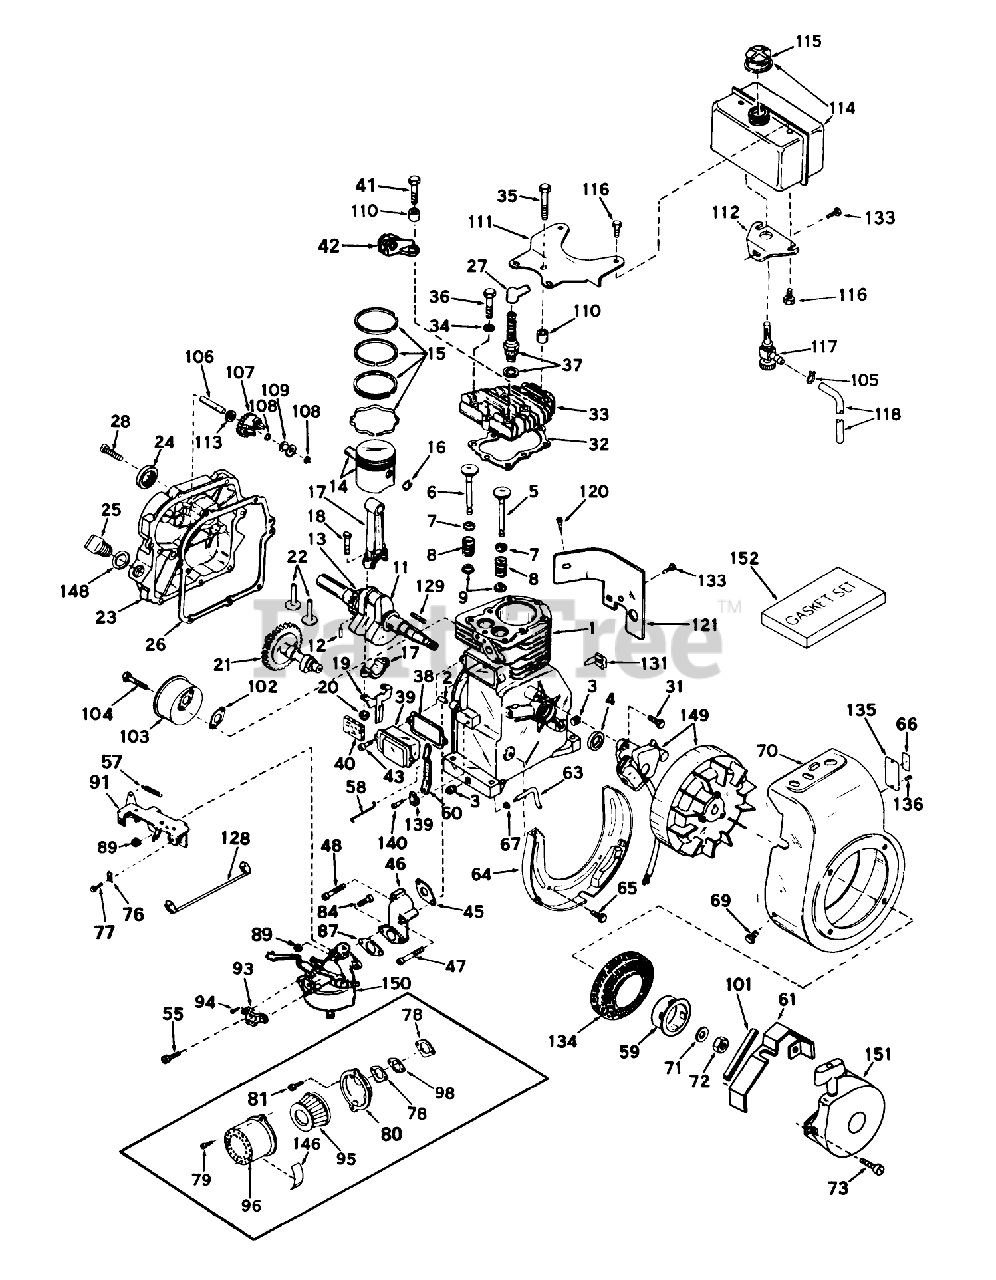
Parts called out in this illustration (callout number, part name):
1	Cylinder Assy. (Incl. Nos. 2,3 4)
2	Pin-Dowel
3	Plug-Drain, Oil (SQH 1/4-18)
4	OIL SEAL
5	Valve, Intake (Incl. Ref. #38, 39 40) (Std.)
5	Valve, Exhaust (1/32" Oversize) (Incl. Nos. 8, 9 10)
6	Valve, Exhaust (Standard) (Incl. Nos. 8, 9 10)
6	Valve, Exhaust (1/32" Oversize) (Incl. Nos. 8, 9 10)
7	Cap-Upper Valve Spring
8	Spring-Valve
9	Cap-Valve, Spring
11	Crankshaft Assy. (Incl.Nos. 12 13)
12	Pin, Groove
13	Gear, Crankshaft
14	Piston Pin Assembly (Incl. 2 of No. 16) (Std.)
14	Piston Pin Assembly (Incl. 2 of No. 16) (.010 Oversize)
14	Piston Pin Assembly (Incl. 2 of No. 16) (.020 Oversize)
15	Piston Ring Set Std.
15	Piston Ring Set .010 O.S.
15	Piston Ring Set .020 O.S.
16	Ring-Retaining, Piston Pin
17	Rod Assy., Connecting (Incl. Ref. #17)
18	Bolt, Connecting
19	53020/22 GIL.HYDRO
20	LOCKNUT
21	Camshaft (Compression Release
22	Lifter-Valve
23	Cover, Cylinder (Incl. Nos. 24, 25, 106 148)
24	Seal, Oil
25	Plug-Fill, Oil
26	Gasket-Cylinder Cover
27	Cover-Spark Plug
28	Screw
31	Screw
32	Gasket-Cylinder Head
33	CYLINDER HEAD
34	Washer
35	Screw Hex Hd. Cap
36	Screw
37	Plug, Spark (J17LM or equiv.)
38	Gasket Breather
39	Breather Assembly (Incl. Nos. 52 84)
40	Element-Breather
41	Screw, Hex Hd. Cap
42	Bracket, Handle Adj.
43	Screw
45	Gasket-Intake
46	Pipe, Intake
47	Screw
48	Screw
55	Screw (8-32 X 5/16)
57	Spring-Extension
58	Jet-Main
59	Starter Cup
60	Lever-Governor
61	Guard, Starter
63	Rod-Governor
64	Baffle, Blower Hsg.
65	Screw (1/4-20x19/32)
66	INSTRUCTION DECAL
67	Washer-Flat
69	Screw
70	Housing, Blower
71	Washer
72	Hex Nut
73	Screw
76	Conduit
77	Screw (10-32 x 3/8)
78	Gasket
79	Screw
80	Bracket
81	Screw, Fil. Hd. Sems
87	Gasket
89	Nut and Lock Washer (1/4-28)
91	Control Assy., Remote Speed (Incl. No. 56)
93	Bracket-Choke
94	Screw (10-32 x 1/2)
95	Element
96	Body
98	Spacer
101	Seal, Snowguard
102	Gasket Exhaust
103	Muffler
104	Screw
105	Clamp-Line, Fuel
106	Shaft-Governor
107	Governor Gear ASM
108	Ring-Retaining
109	Spool-Governor
110	pacer
111	Bracket, Fuel Tank-Upper
112	Bracket, Fuel Tank Lower
113	Washer-Flat
114	Tank Assy., Fuel (Incl. Ref. 112 115)
115	Cap, Fuel
116	Screw
117	Fitting Shut-off, Fuel
118	Line-Fuel
120	Screw
121	Extension-Blower
128	Wire, Ground
129	Key Flywheel
131	Clip-Wire
133	Screw (1/4-20x19/32)
134	Screen, Air
135	IDENTIFICATION PLATE
136	DRIVE STUD
139	Clamp-Lever, Governor
140	Screw
146	Decal
148	Gasket
149	Magneto
150	Carburetor
151	Starter Assy., Rewind
152	Gasket Set (Incl. items marked*
